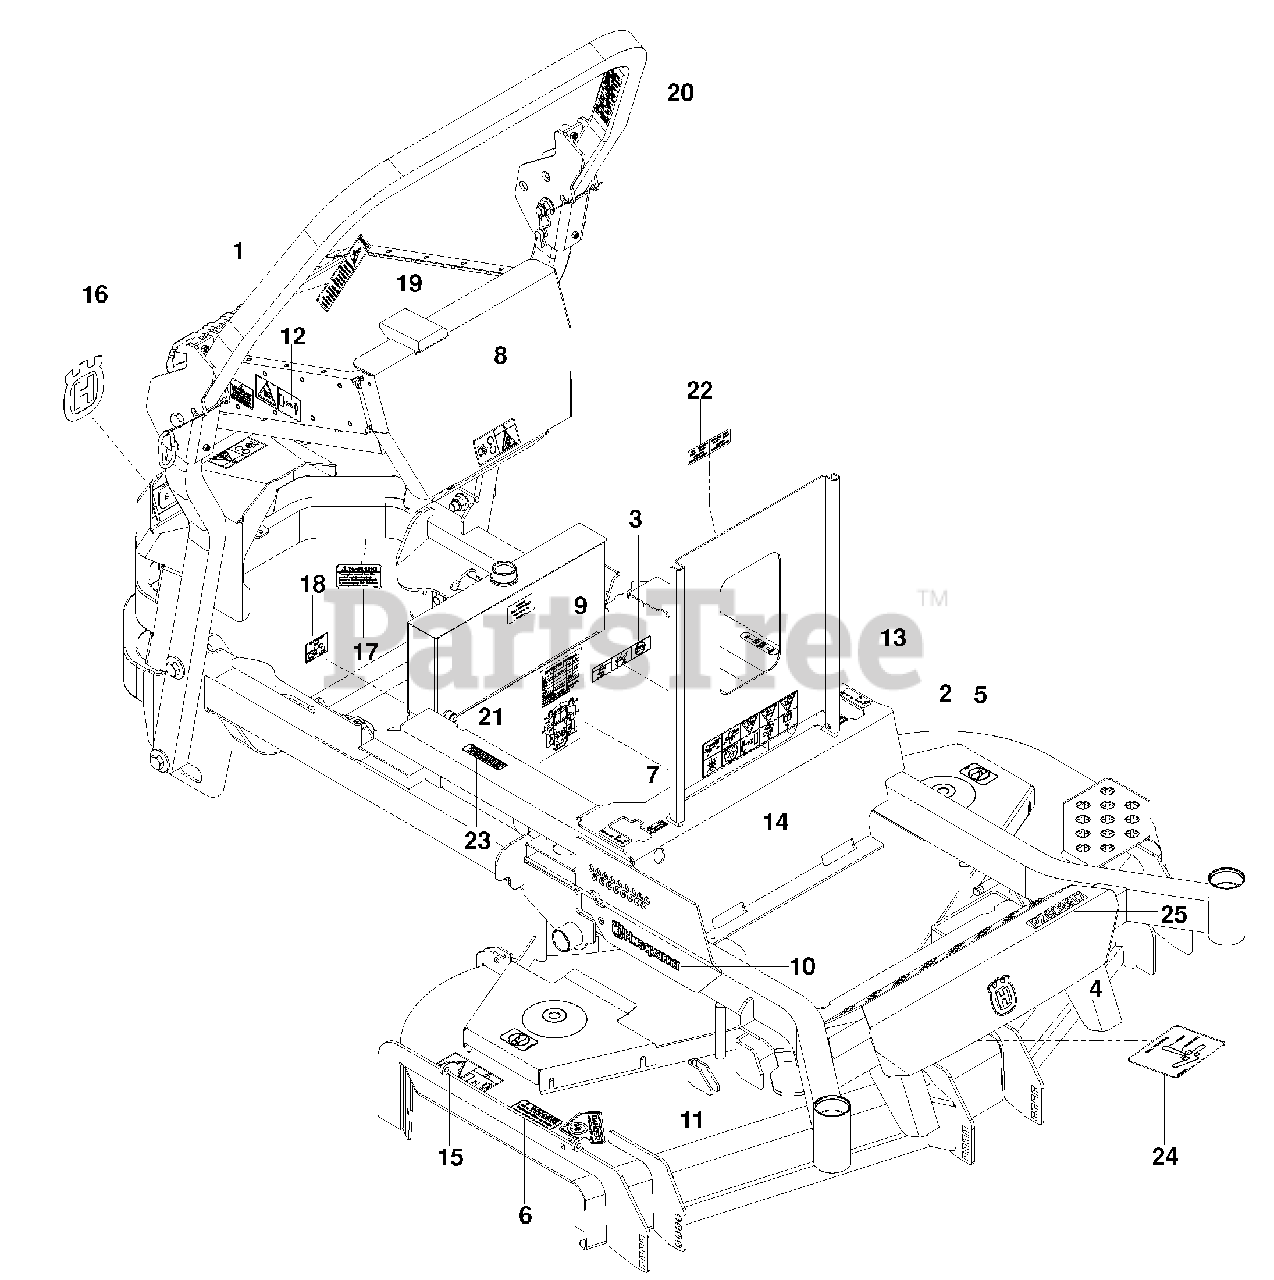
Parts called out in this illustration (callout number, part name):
1	Decal, Debris Screen
2	Decal, Motion Control
3	Decal, Battery Warning
4	Decal, Crown H, Sm
5	Decal, No Step
6	Decal, Warning
7	Decal, F.S.T
8	Decal, Danger Belt Drives
9	Decal, Oil Tank
10	Decal, Husqvarna Hood
11	Decal, Cpsc
12	Decal, Hot
13	Decal, Park Brake
14	Decal, Warning
15	Decal, Severing
16	Decal, Crown H, Lg
17	Decal, Exhaust
18	Decal, Hydro Belt
19	Decal, Rops, Warning
20	Decal, Rops, Diesel
21	Decal, Service, Diesel
22	Decal, Fuse, Diesel
23	Decal, Spark Arrestor
24	Decal, Belt Routing
25	Decal, Pz6029D
